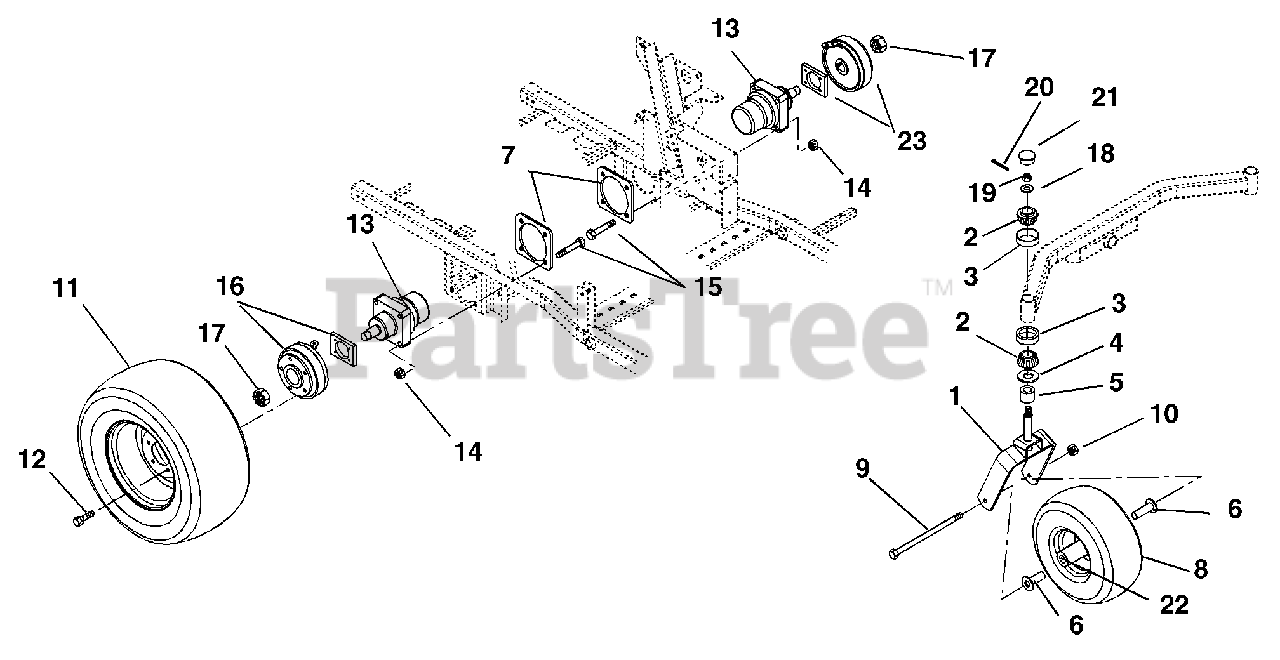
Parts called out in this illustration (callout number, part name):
1	Fork, Front
2	Bearing, Cone w/ Grease
3	Bearing, Cup 1.980 x .420
4	Bearing Seal 1.5 x 2 x .18
5	Spacer, PM, 1.03 I.D. x 1.5 O.D. x .375
6	Spacer, Wheel
7	Plate, Motor Support
8	Wheel/Tire Assembly
8	Tire, 15 x 6-6
9	Bolt, Hex .50-13 x 9.00 Grade 5
10	Nut, Locking Center .50-13
11	Tire/Wheel Assembly 24 x 12-12
11	Tire, Turfmaster 24 x 12-12
12	Bolt, Lug .50-20 x 1.38 Grade 8, 60 Degree
13	Hydraulic Wheel Motor
14	Nut, Locking Top Flange .50-13
15	Bolt, Wheel Motor .50-13 x 2.75
16	Brake, Right Hand Park
17	Nut , Lock Jam Patch
18	Washer, Flat Steel .755 x 1.375 x .062
19	Nut, Slotted .75-16
20	Pin, Cotter .16 x 1.00
21	Cap, Dust
22	Bearing, 25mm I.D. x 52mm OD x 15mm
23	Brake, Left Hand Park
